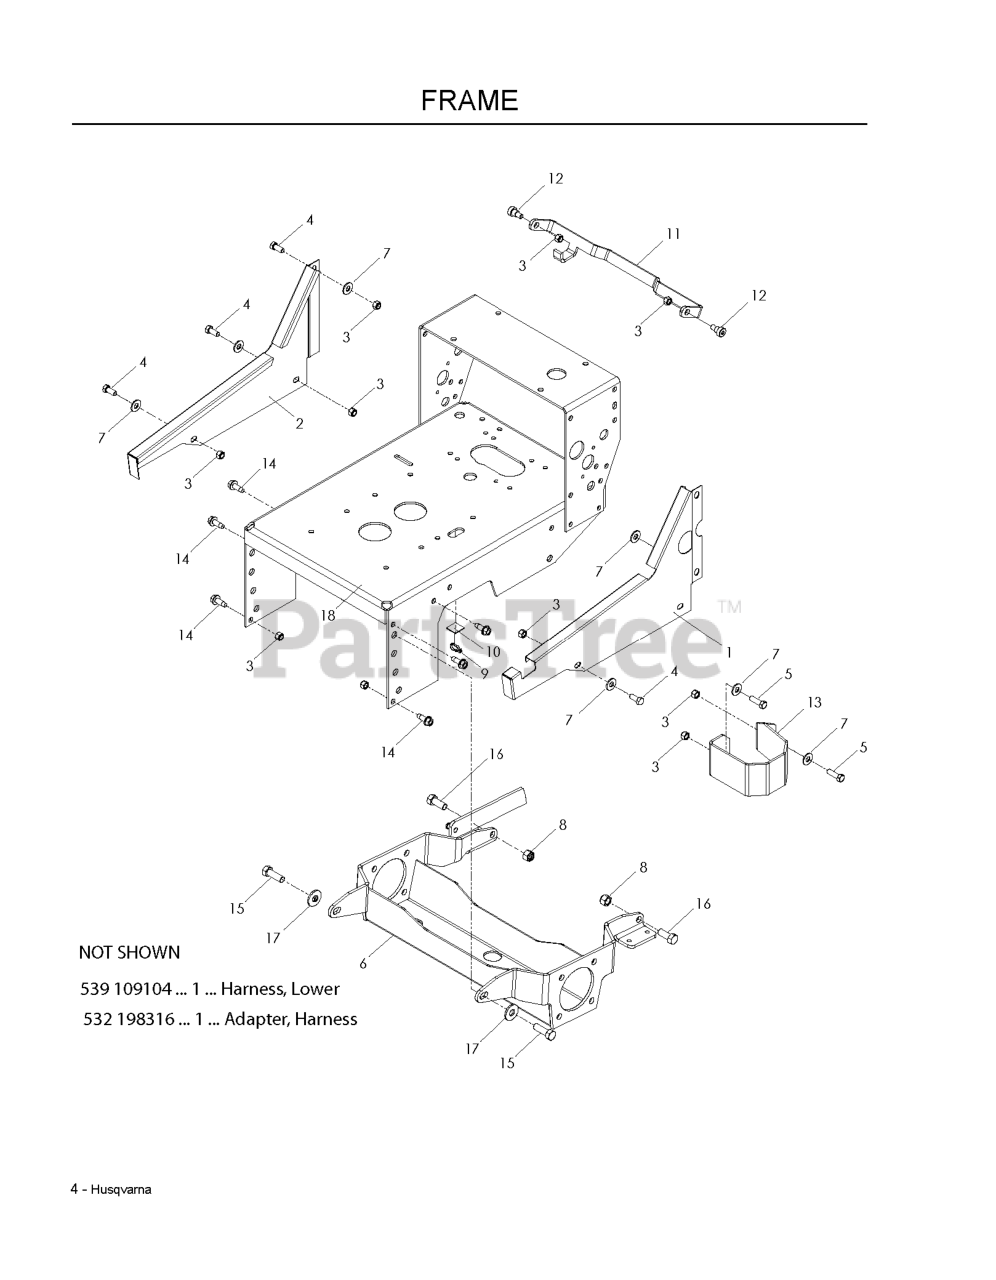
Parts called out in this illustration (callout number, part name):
1	PANEL - SIDE RH PAINTED
2	PANEL - SIDE LH PAINTED
3	NUT 3/8-16 NYLOC
4	HCS 3/8-16 X 7/8 GR 5 ZD
5	HCS 3/8C X 1 1/4 GR5
7	WASHER 3/8 FLAT
8	NUT 1/2-13 HEX NYLOC ZD
9	TIE, PLASTIC
10	MOUNTING BLOCK CABLE TIE
11	BAR THROW OUT, PAINTED
12	SB 3/8-16 X 3/8 SKT HD ZD
13	GUARD FILTER PAINTED
14	BOLT 3/8-16 X 1.0
15	HCS 1/2-13 X 1-1/2 GR 5 ZD
16	HCS 1/2-13 X 1-1/4
17	WASH USS FLAT 1/2
18	ENGINE CHASSIS W/DECAL
